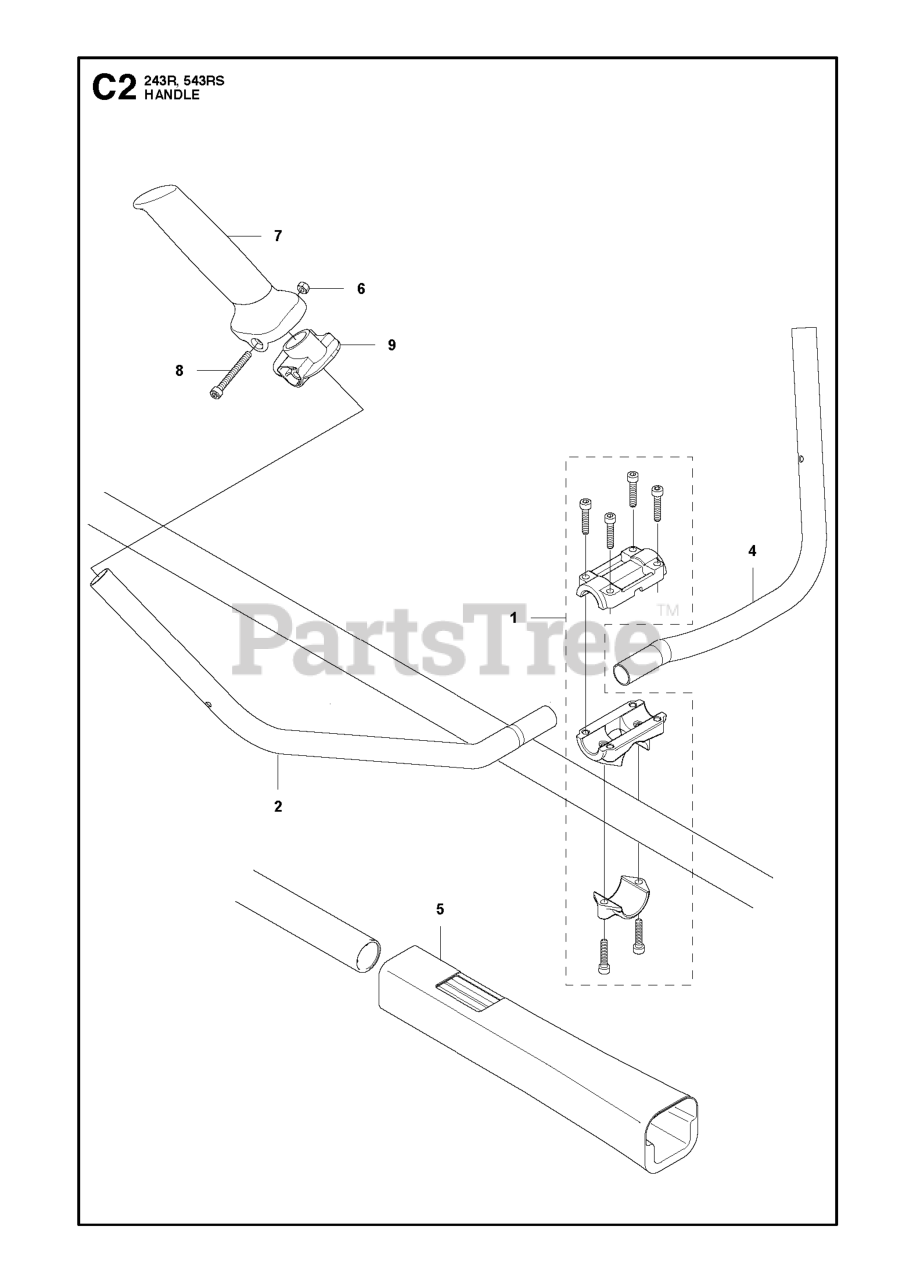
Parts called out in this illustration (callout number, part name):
1	HANDLE BRACKET ASSY 243R
2	HANDLE(L)-A
5	PROTECTOR (RPLS 405017110)
